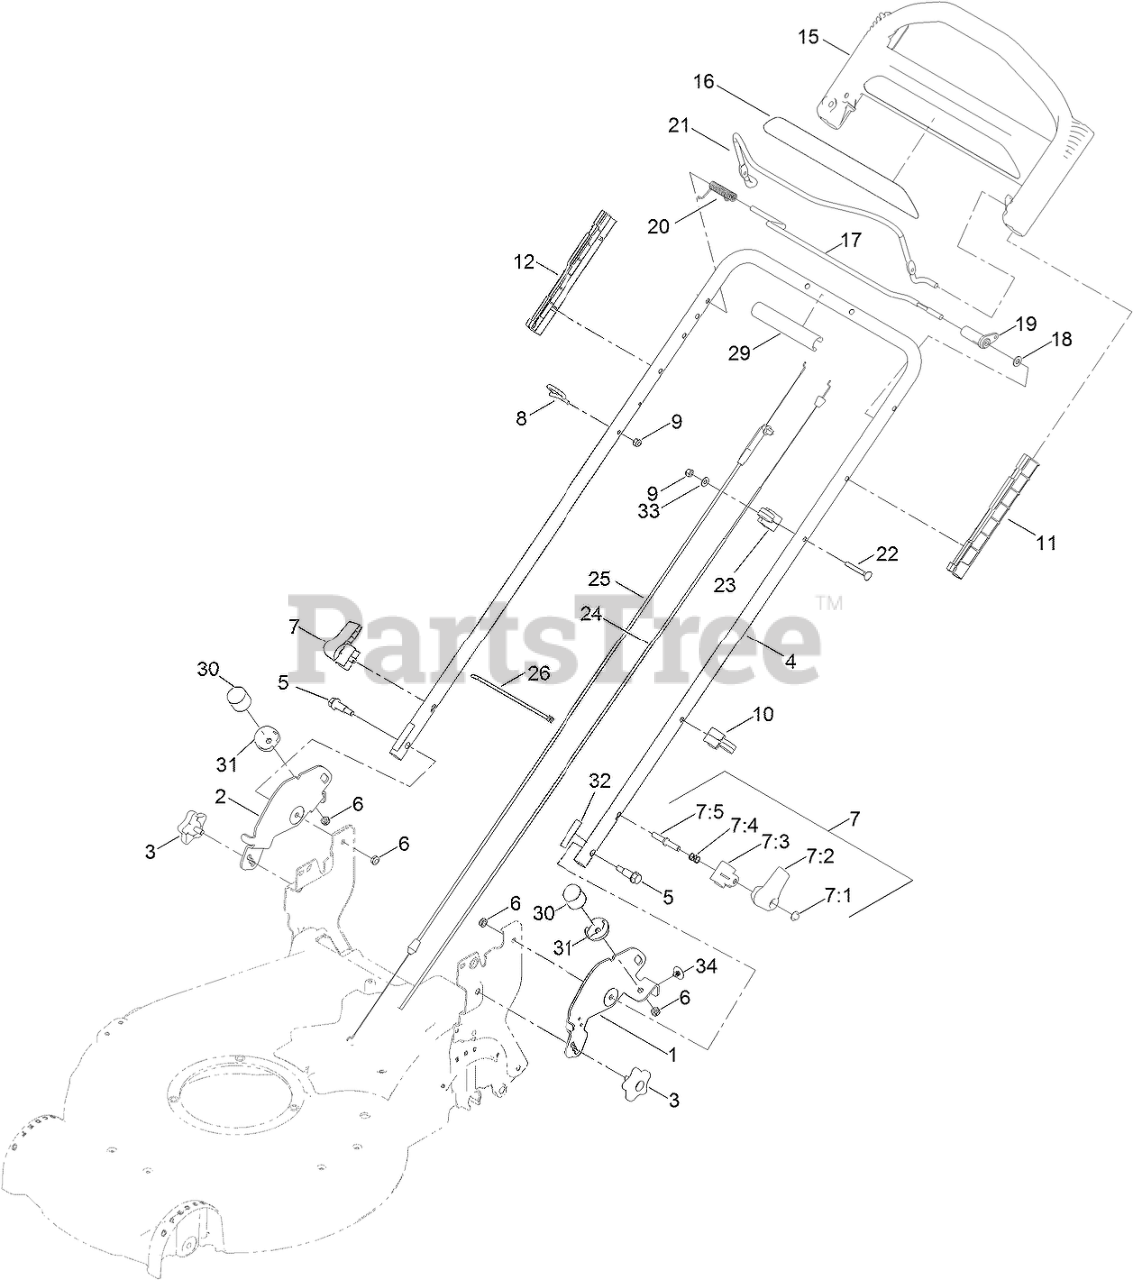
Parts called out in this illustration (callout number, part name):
1	BRACKET-FLOAT, LH
2	BRACKET-FLOAT, RH
3	KNOB-HANDLE
4	HANDLE-UPPER
5	BOLT-SHOULDER
6	NUT-LOCK, NI
7	QUICK RELEASE ASM
7:1	NUT-PUSH
7:2	LEVER-RELEASE
7:3	ANCHOR-SPRING
7:4	SPRING-COMPRESSION
7:5	ROD-RELEASE
8	GUIDE-ROPE
9	NUT-LOCK, NI
10	GUIDE-CABLE
11	GUIDE-LH
12	GUIDE-RH
15	HANDLE-CONTROL
17	BAR-CONTROL, TRACTION
18	WASHER-PLAIN
19	LEVER-TRACTION
20	SPRING-TORSION
21	BAIL-BRAKE
22	SCREW
23	ANCHOR-CABLE
24	CABLE-TRACTION
25	CABLE-BRAKE
26	TIE-CABLE
29	HANDLE-COVER
30	BUMPER-RUBBER
31	COVER-BUMPER
32	DECAL-FLEX
33	WASHER-FLAT
34	CLIP-TREE
